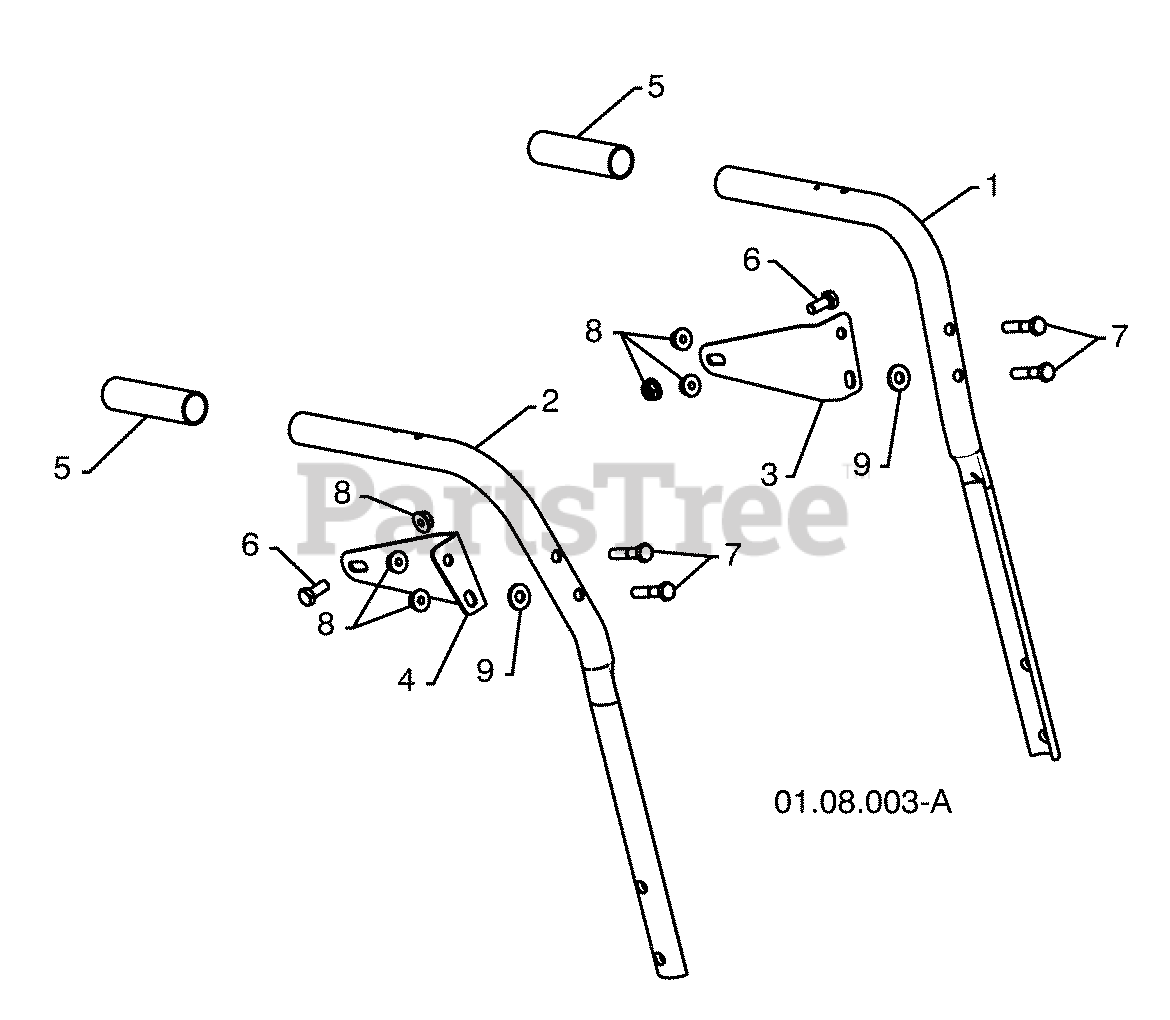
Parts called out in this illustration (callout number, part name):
1	PLOW HANDLE LH
2	PLOW HANDLE RH
3	PANEL BRACKET LH
4	PANEL BRACKET RH
5	HANDLE GRIP
6	SCREW 5/16--18 X .750
7	SCREW 5/16--18 X 1.50
8	NUT 5/16--18
